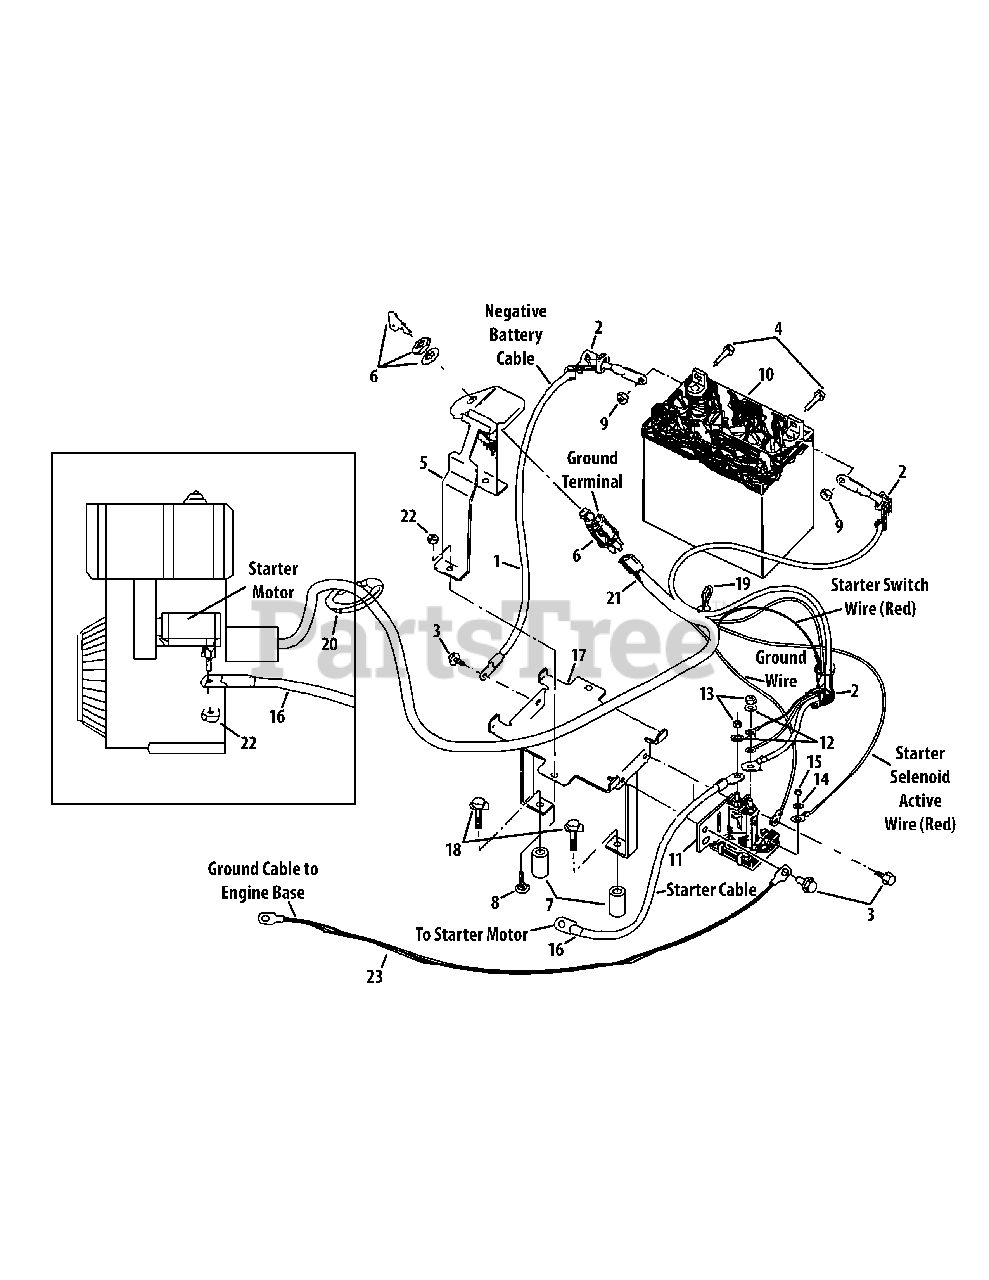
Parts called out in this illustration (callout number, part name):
1	Battery Cable
2	Terminal Insulating Boot
3	TT-Screw, 1/4"-2 x 1/2"
4	Hex Bolt, 1/4-20 x 5/8"
5	Battery Hold-down Clamp w/ Att. Key Switch Plate
6	Key Switch (Incl. 2 Keys)
8	Carriage Bolt, 1/4-20 x 1-1/4"
9	Hex Nut, 1/4-20
10	12-Volt Battery
11	Starter Solenoid
12	Lockwasher, 5/16"
13	Hex Nut, 5/16-24
14	External Tooth Lockwasher
15	Hex Nut, #10-32
16	Battery Cable
17	Battery Bracket
18	Hex Head Screw, 3/8-16 x 2.75"
19	Plastic Tie
20	Plastic Tie
21	Wire Harness & Connecting Terminal Assembly
22	Flangelock Nut, 1/4-20
23	Ground Cable
